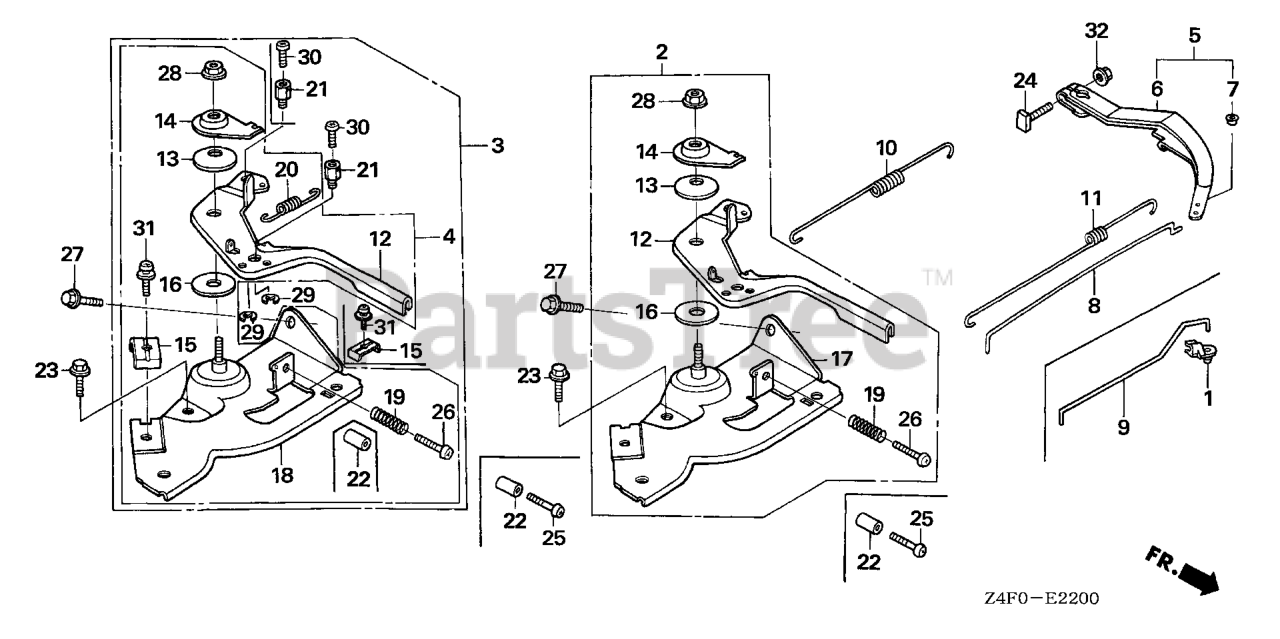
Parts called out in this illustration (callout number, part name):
3	CONTROL ASSY. (REMOTE)
6	ARM, GOVERNOR
8	ROD, GOVERNOR
10	SPRING, GOVERNOR
11	SPRING, THROTTLE RETURN
12	LEVER, CONTROL
13	SPRING, LEVER
14	WASHER, CONTROL LEVER
15	HOLDER, CABLE
16	SPACER, CONTROL LEVER
18	BASE, CONTROL
19	SPRING, CONTROL ADJUSTING Use from Engine SN 2327377.
20	SPRING, CABLE RETURN
21	HOLDER, WIRE
23	BOLT, FLANGE (6X12) (CT200)
24	BOLT, GOVERNOR ARM
26	SCREW, PAN (5X25)
27	BOLT, FLANGE (6X20) (CT200)
28	NUT, SELF-LOCK (6MM)
29	CIRCLIP (5MM) Use from Engine SN 2327377.
30	SCREW, PAN (4X6)
31	SCREW, PAN (5X16)
32	NUT, FLANGE (6MM)
